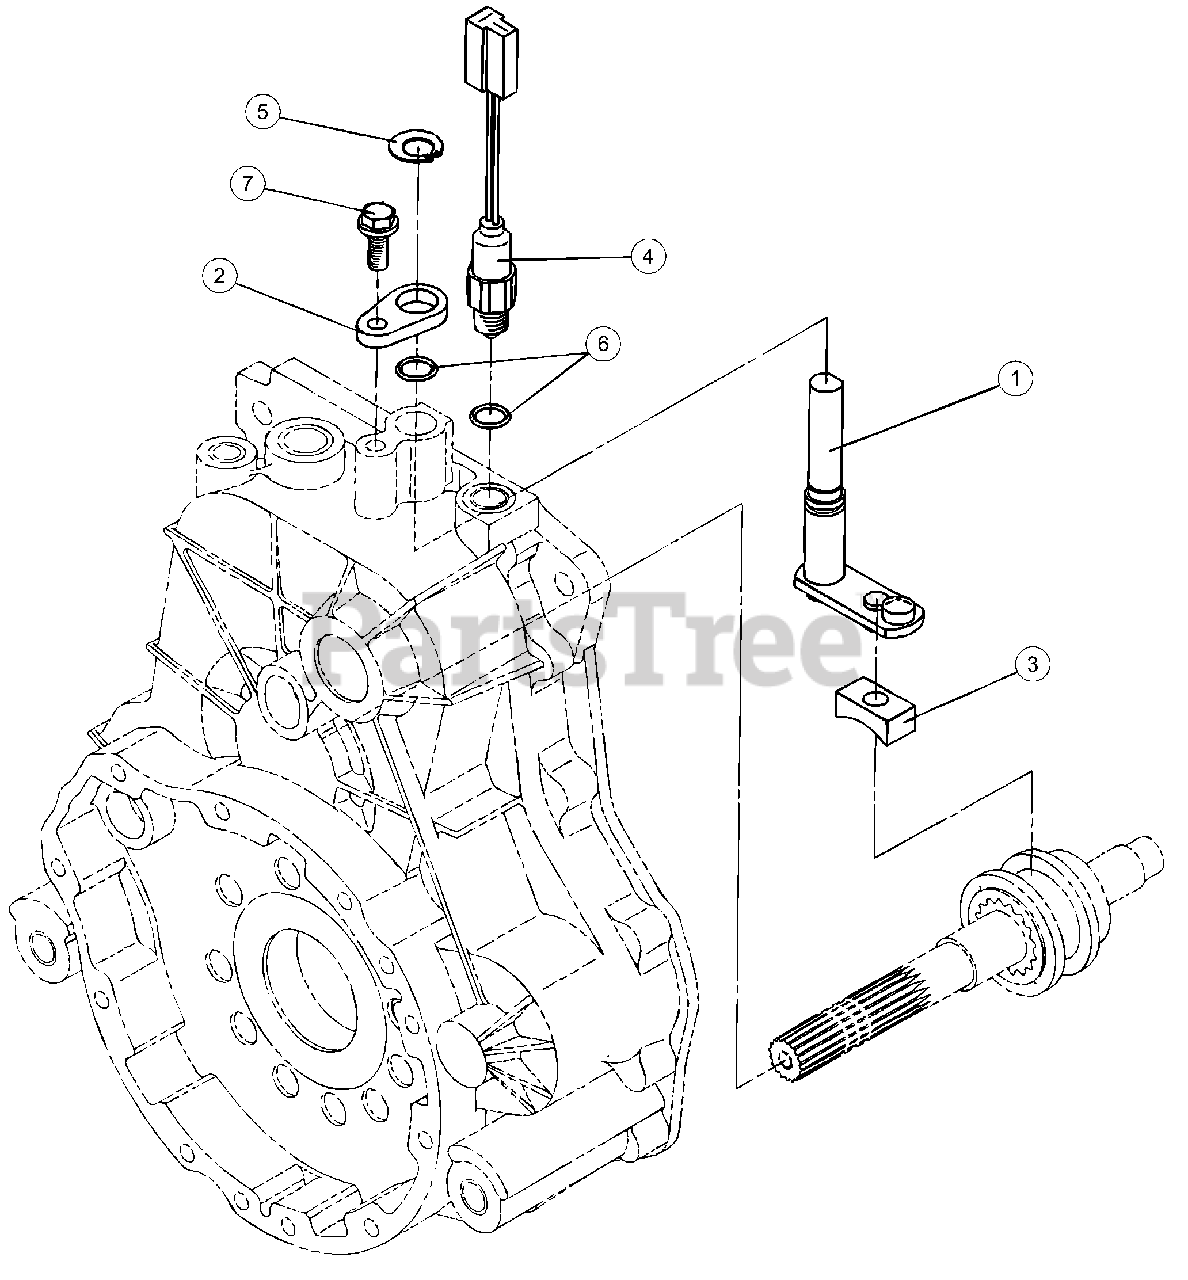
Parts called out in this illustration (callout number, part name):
1	Arm, Shift
3	Block, Shift
4	Switch
6	Packing, P 12.5
7	Tapping Screw, 8 x 20
